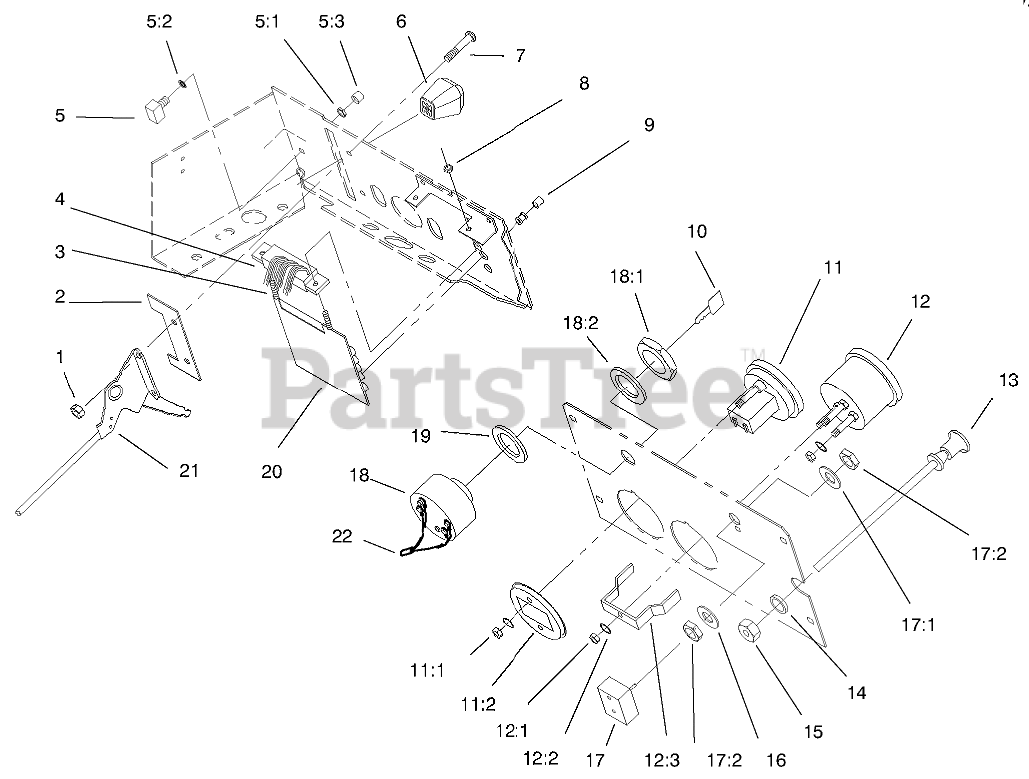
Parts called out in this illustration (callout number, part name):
1	Nut
2	STOP-THROTTLE
3	Screw
4	P.C. BOARD HARNESS
5	SWITCH-PUSH BUTTON
5:1	NUT F/W 116796
5:2	Washer
5:3	BUTTON F/W 116796
7	SCRW-PHC
8	NUT-HEX
9	ASSY LENS & BUSHING
10	KEY-IGNITION
11	Hourmeter
11:1	NUT-HEX, KEPS
11:2	Retainer
12	VOLTMETER
12:1	NUT-HEX
12:2	WASHER-LOCK
12:3	CLAMP-MOUNTING
13	CONTROL-CHOKE
14	WASHER-FLAT
15	NUT-HEX PALNUT
16	WASHER
17	SWITCH-LIGHTS
17:1	TAB-WASHER
18	IGNITION SWITCH ASM
18:2	WASHER-LOCK
19	WASHER
20	Board-Pc
21	CONTROL-THROTTLE
